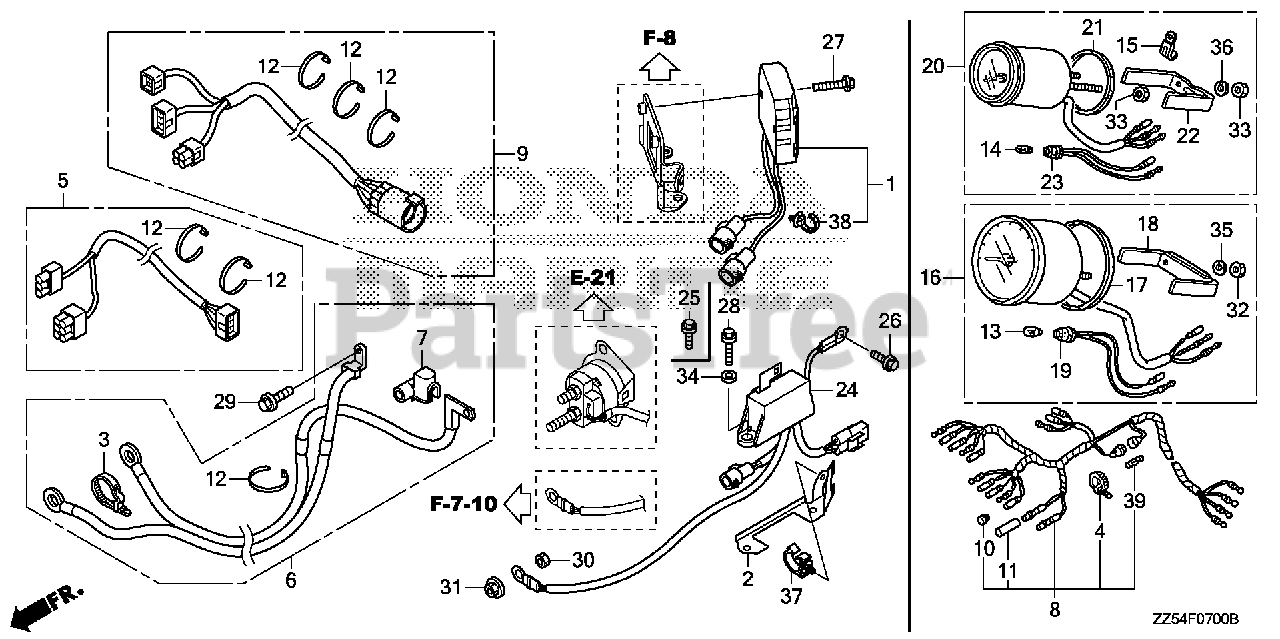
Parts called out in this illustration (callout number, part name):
1	RECTIFIER ASSY., REGULATOR
2	BRACKET A, HARNESS CLIP
3	BAND, WIRE
6	CABLE ASSY., STARTER
7	COVER, TERMINAL
12	TIE, CABLE (NATURAL 2.4X92) Use up to Frame SN 1300359.
25	BOLT, FLANGE (6X12) (CT200)
27	BOLT, FLANGE (6X25)
29	BOLT, FLANGE (8X18)
30	NUT, HEX. (6MM)
37	CLIP, WIRE HARNESS
38	CLIP, HARNESS BAND (96.9MM) (NATURAL)
